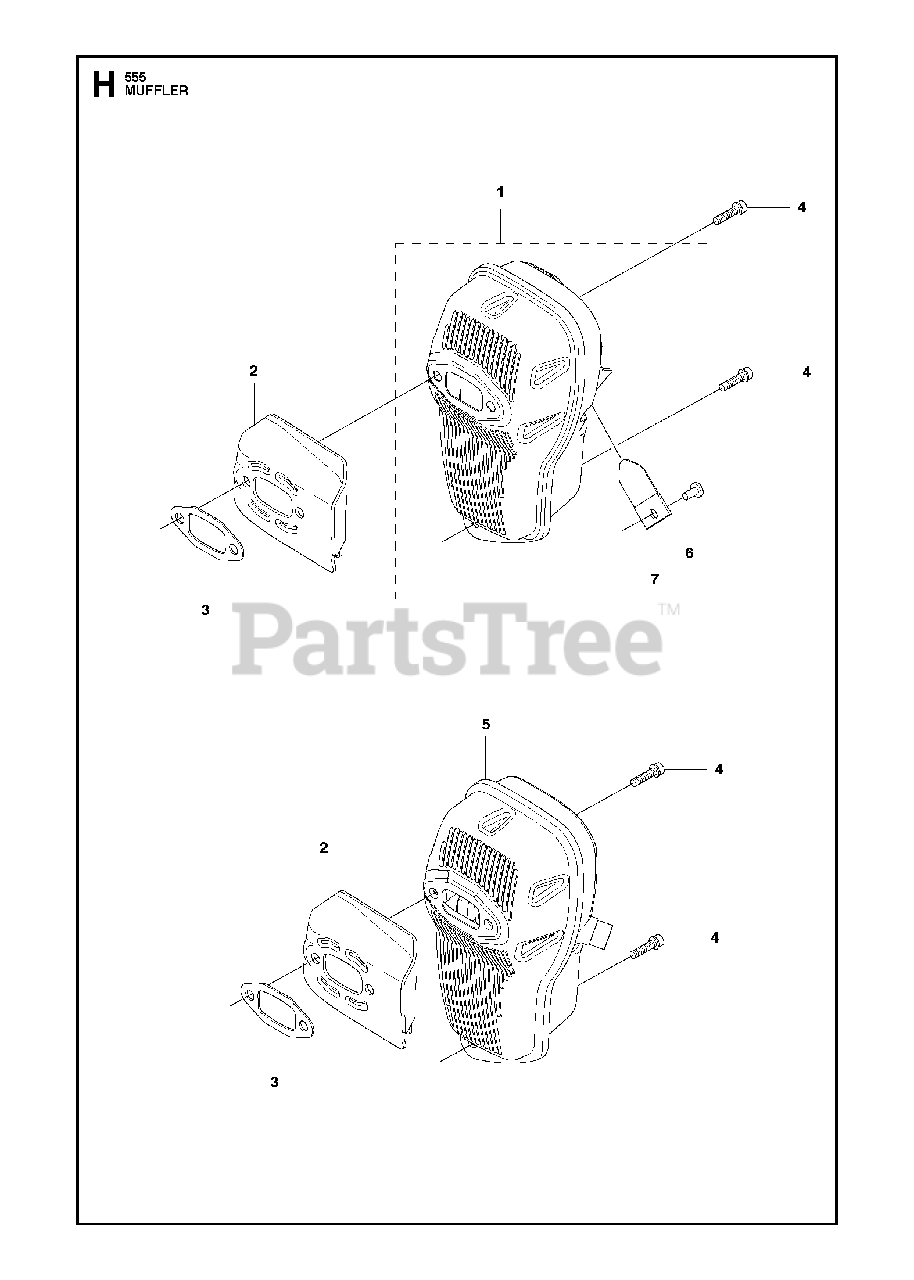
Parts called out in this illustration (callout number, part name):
1	MUFFLER ASSY
5	MUFFLER
6	SCREW
7	SPARK ARRESTOR SCREEN
